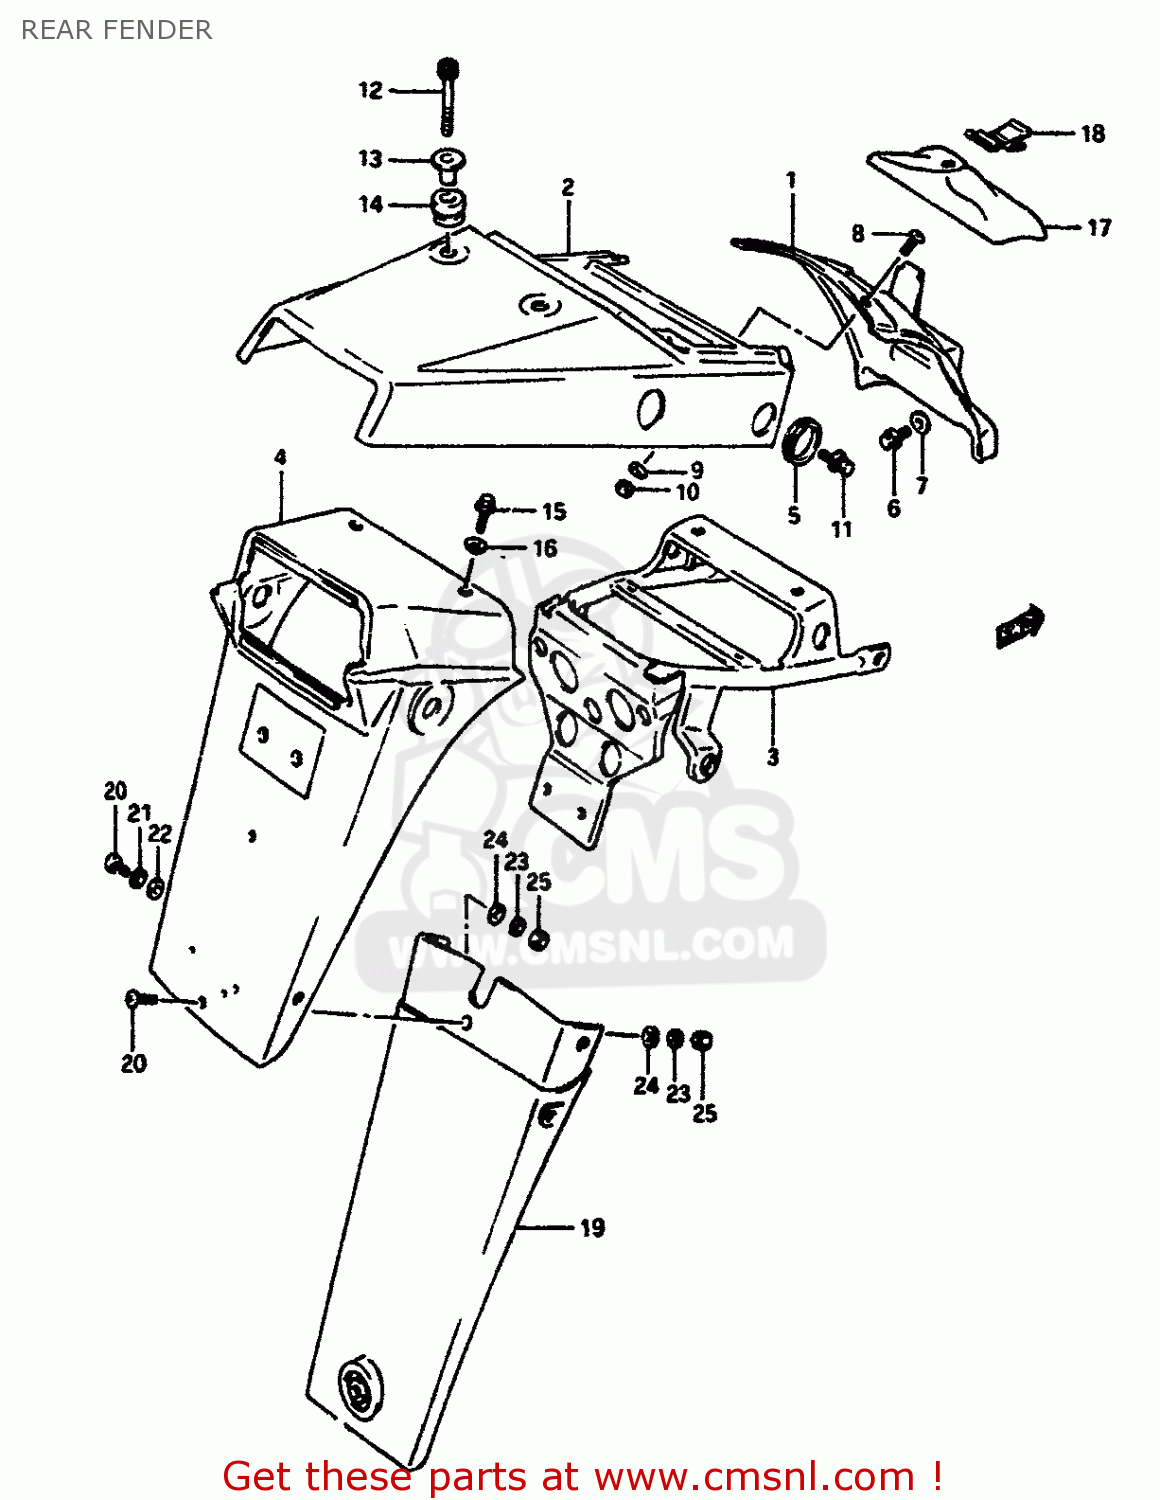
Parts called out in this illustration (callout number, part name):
1	BODY,REAR FENDER FRONT
2	BODY,REAR FENDER REAR (RED)
3	REINFORCEMENT,FENDER
4	EXTENSION,REAR FENDER
5	GROMMET
6	BOLT
7	WASHER
8	SCREW
9	WASHER
10	NUT 8MM
11	BOLT
12	BOLT ,8X50
13	SPACER(8.6X12X18.5)
14	CUSHION
15	BOLT
16	WASHER
17	TOOL SET
18	BAND
19	MUD GUARD,REAR FENDER
20	SCREW
21	WASHER
22	WASHER
23	WASHER,LOCK
24	WASHER(6.5X16X1.2)
25	NUT
